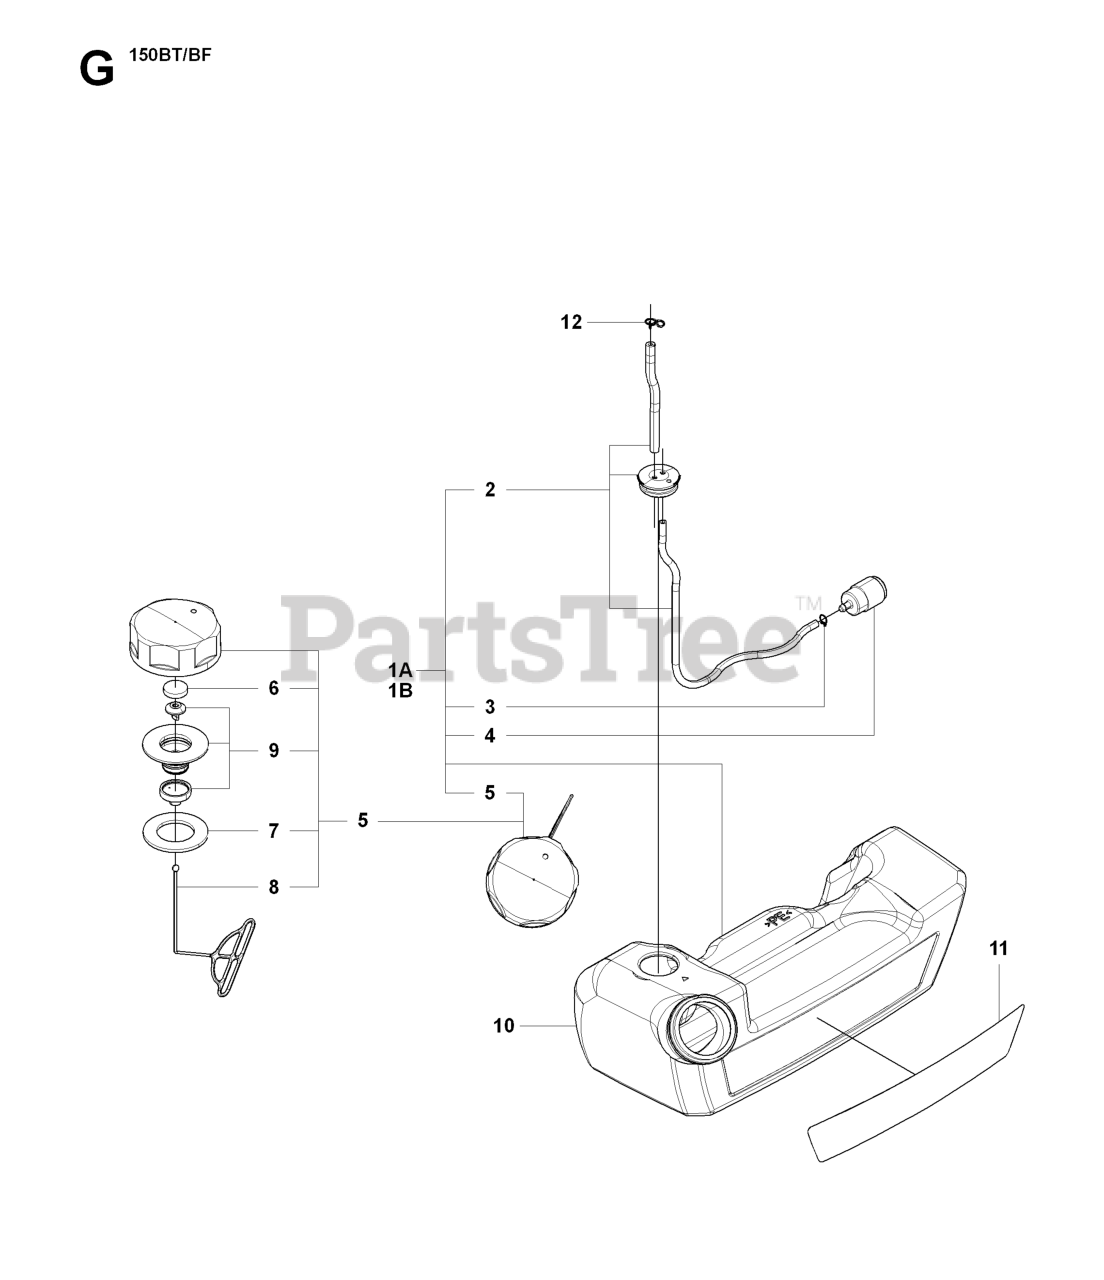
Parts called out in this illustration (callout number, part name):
1A	TANK ASSY
1B	TANK ASSY
2	PIPE C
3	CLIP
4	FILTER
5	ASSY FUEL CAP
6	FILTER
7	PACKING
9	HOLDER-A
12	CLIP
